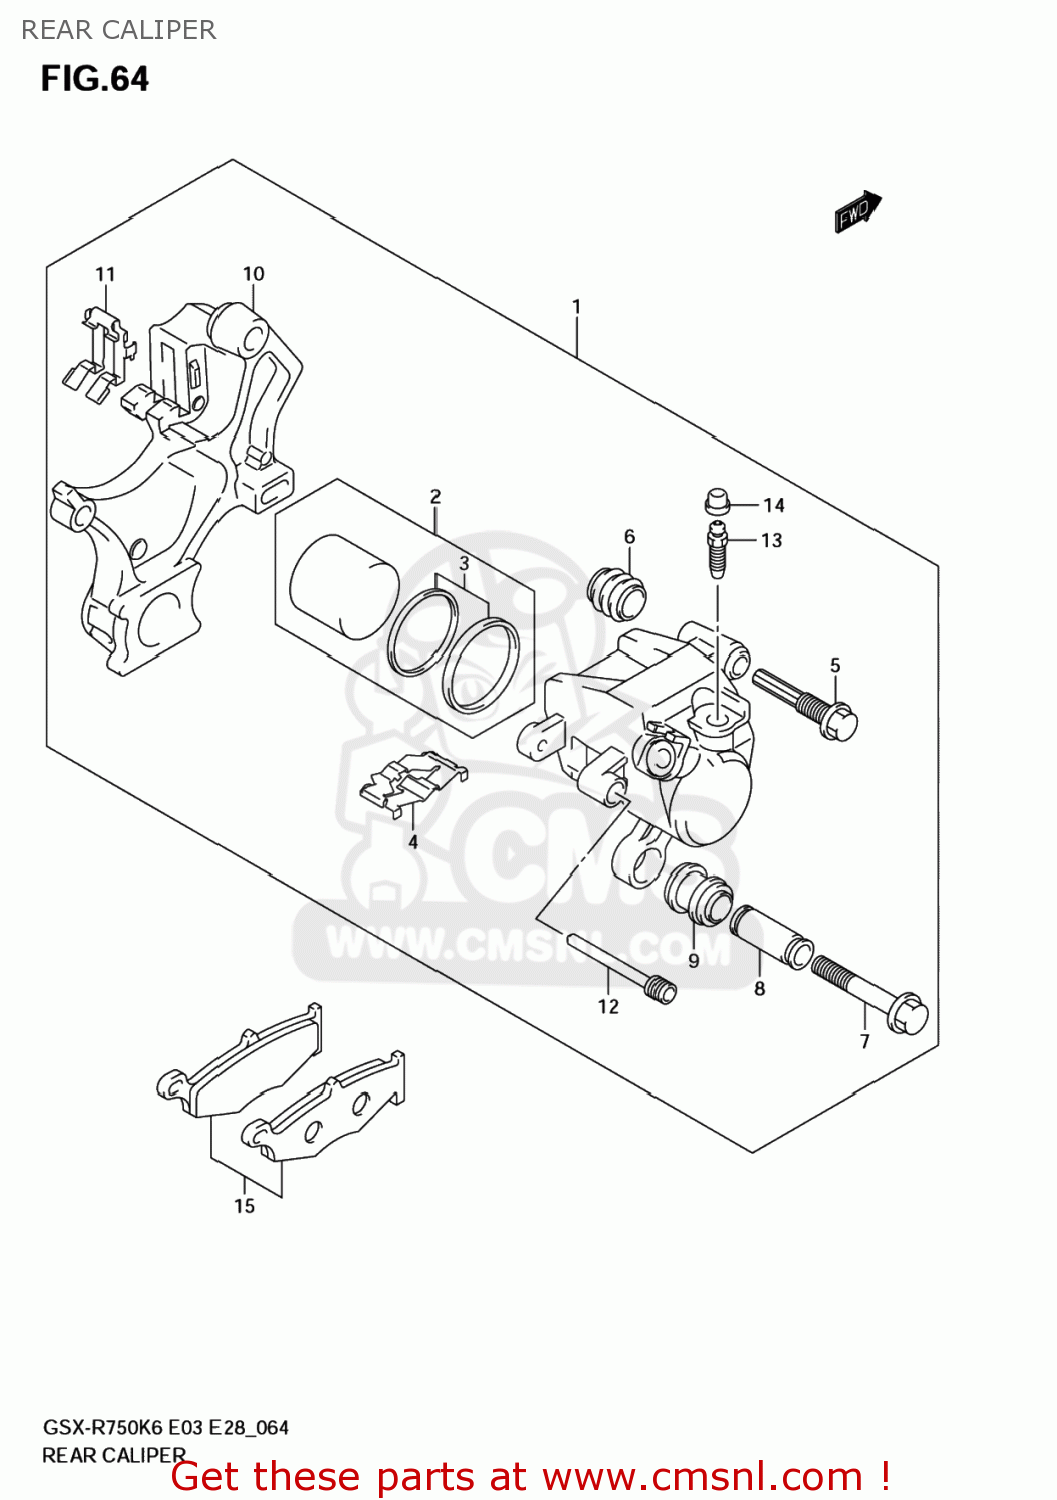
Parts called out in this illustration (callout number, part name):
1	CALIPER ASSY,RR
2	PISTON SET
3	SEAL SET,PISTON
4	SPRING,PAD
5	PIN,BOLT
6	BOOT,AXLE
7	BOLT
8	SLEEVE
9	BOOT,SLEEVE
10	BRACKET
11	RETAINER
12	PIN,PAD
13	BLEEDER
14	CAP,BLEEDER PLUG
15	PAD SET (NAS)
